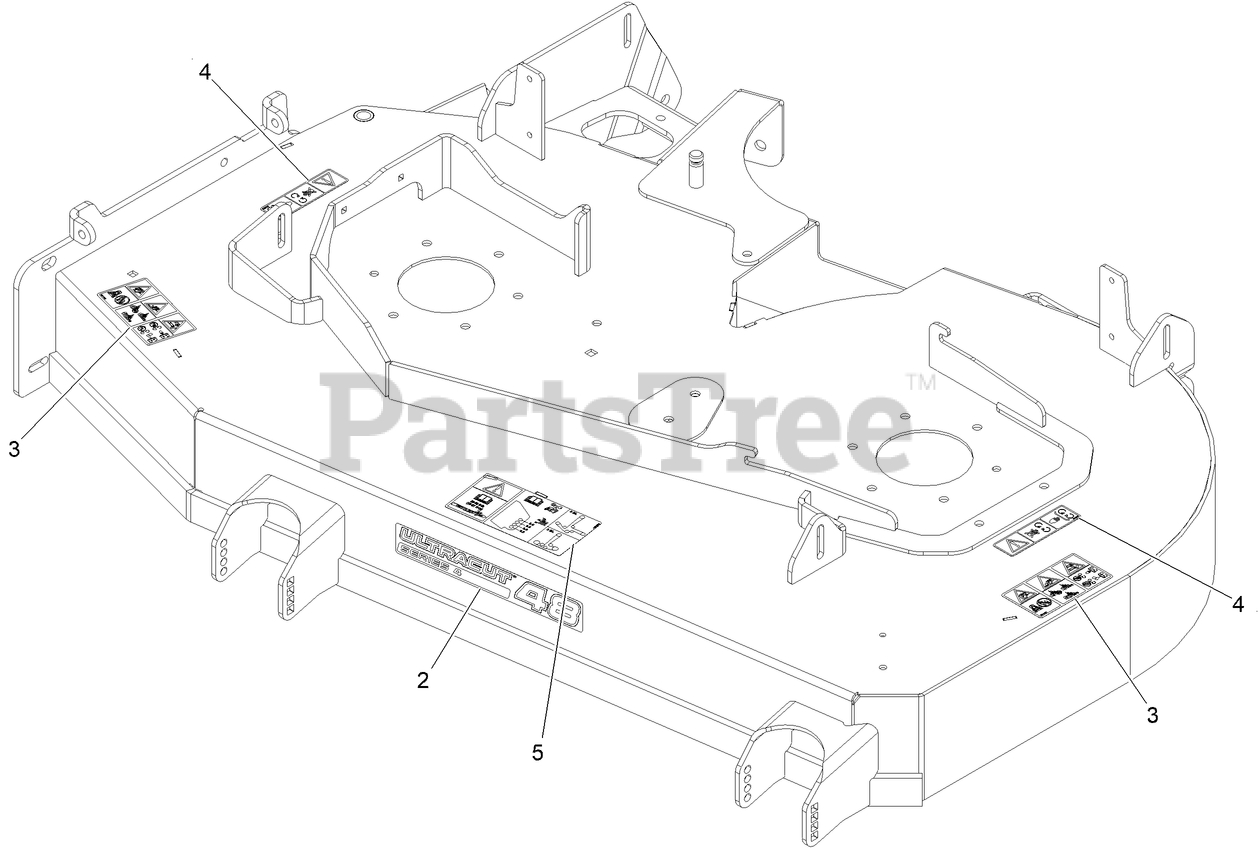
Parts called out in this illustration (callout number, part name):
2	DECAL, 484
3	DECAL-DANGER THROWN OBJECTS
4	DECAL-COVER, MISSING
5	Decal-Anti-Scalp-Belt Routing
